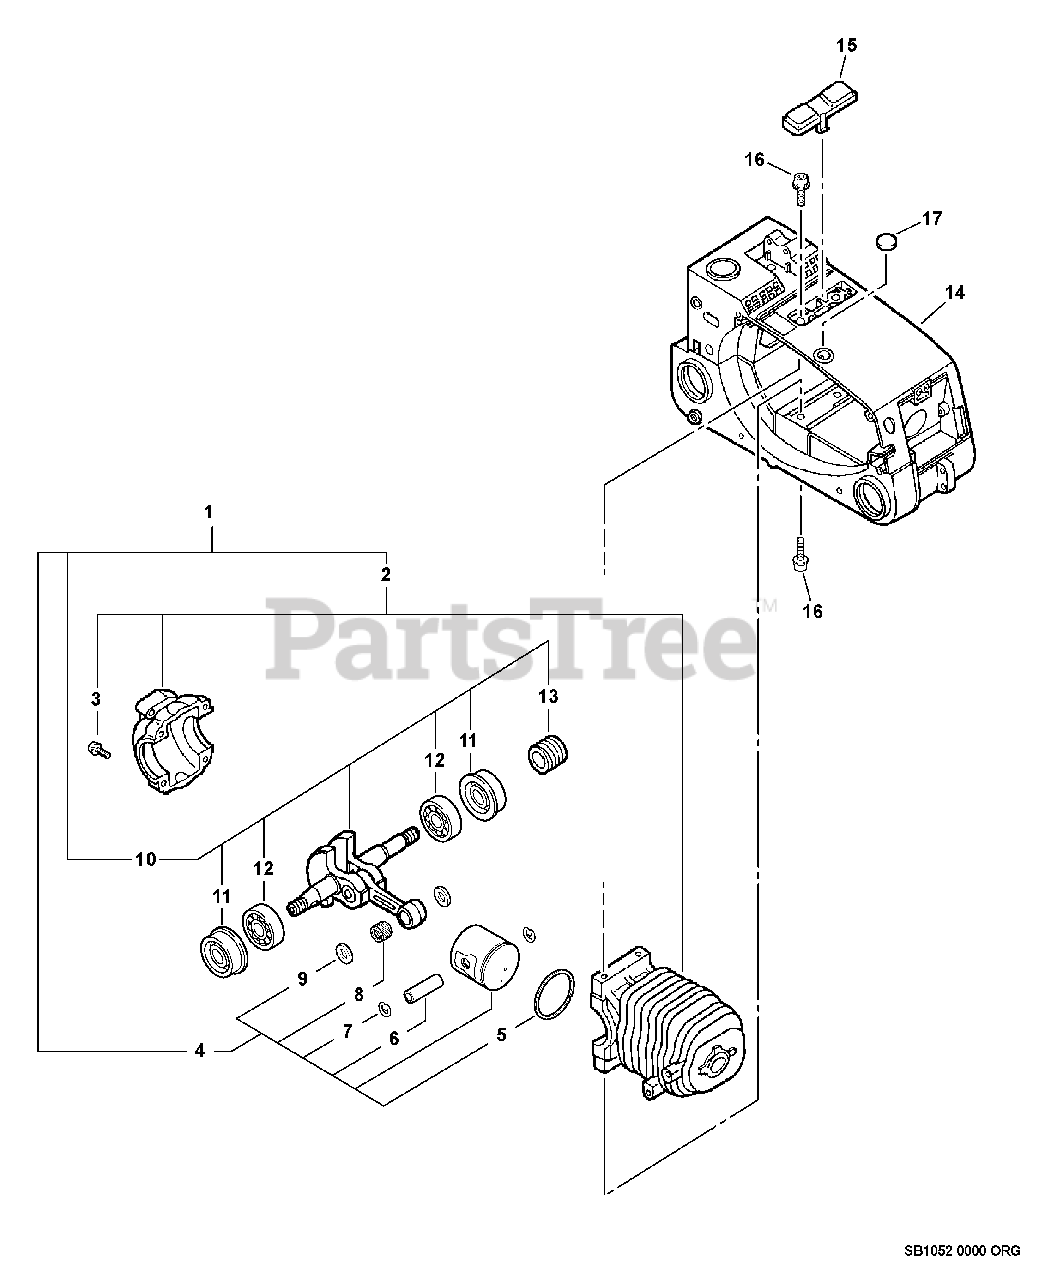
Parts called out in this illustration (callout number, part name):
1	SHORT BLOCK
2	CRANKCASE KIT
3	SCREW 5×25
4	PISTON KIT
5	RING, PISTON
6	PIN, PISTON
7	RING, SNAP
8	BEARING, NEEDLE 8
9	WASHER, THRUST
10	CRANKSHAFT ASSY
11	SEAL, OIL 12
12	BEARING, BALL - 6201 C3
13	GEAR, WORM
14	COVER, ENGINE - ORANGE
15	COVER, TOP
16	BOLT 5×16
